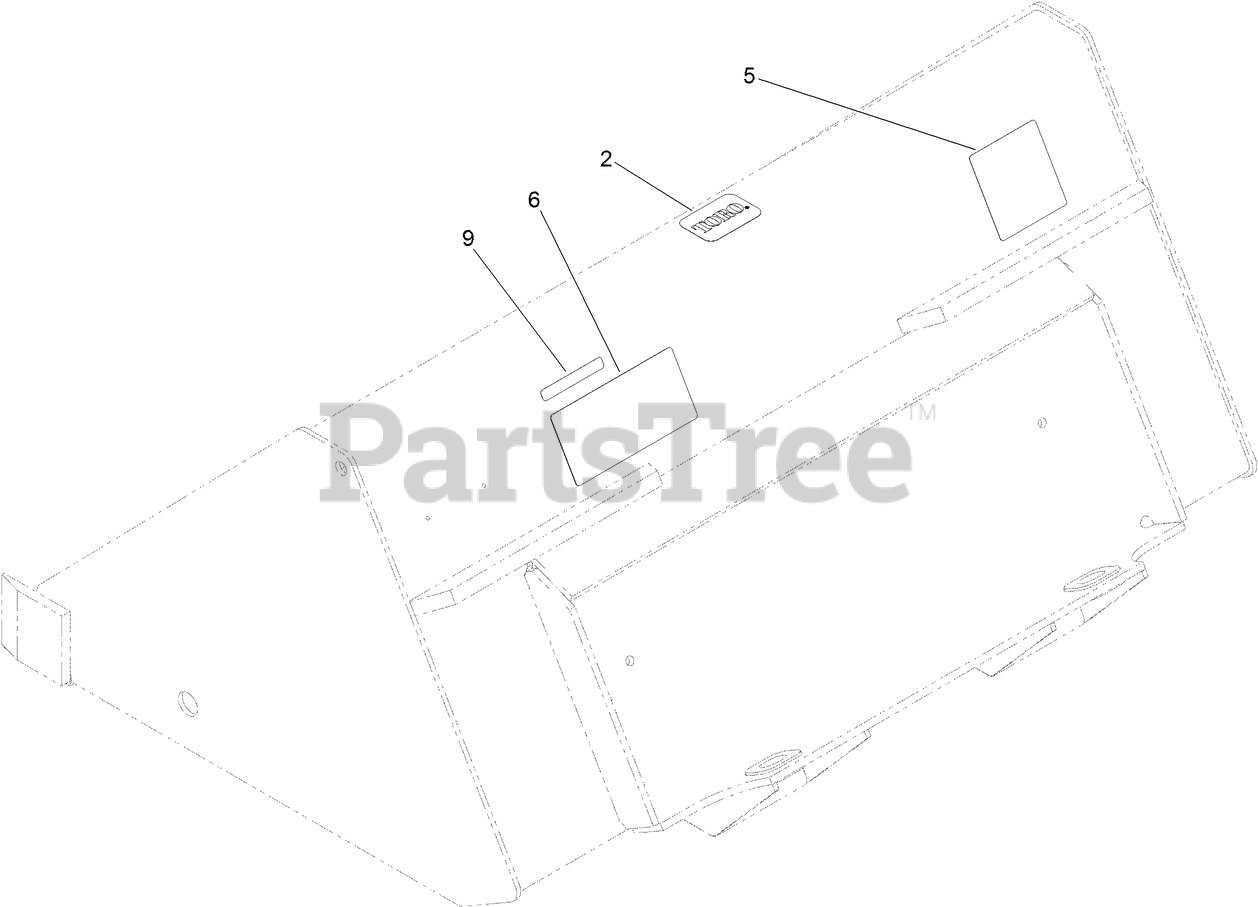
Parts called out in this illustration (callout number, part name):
2	DECAL
5	DECAL
6	DECAL-LOAD RATING
9	DECAL-WARNING
